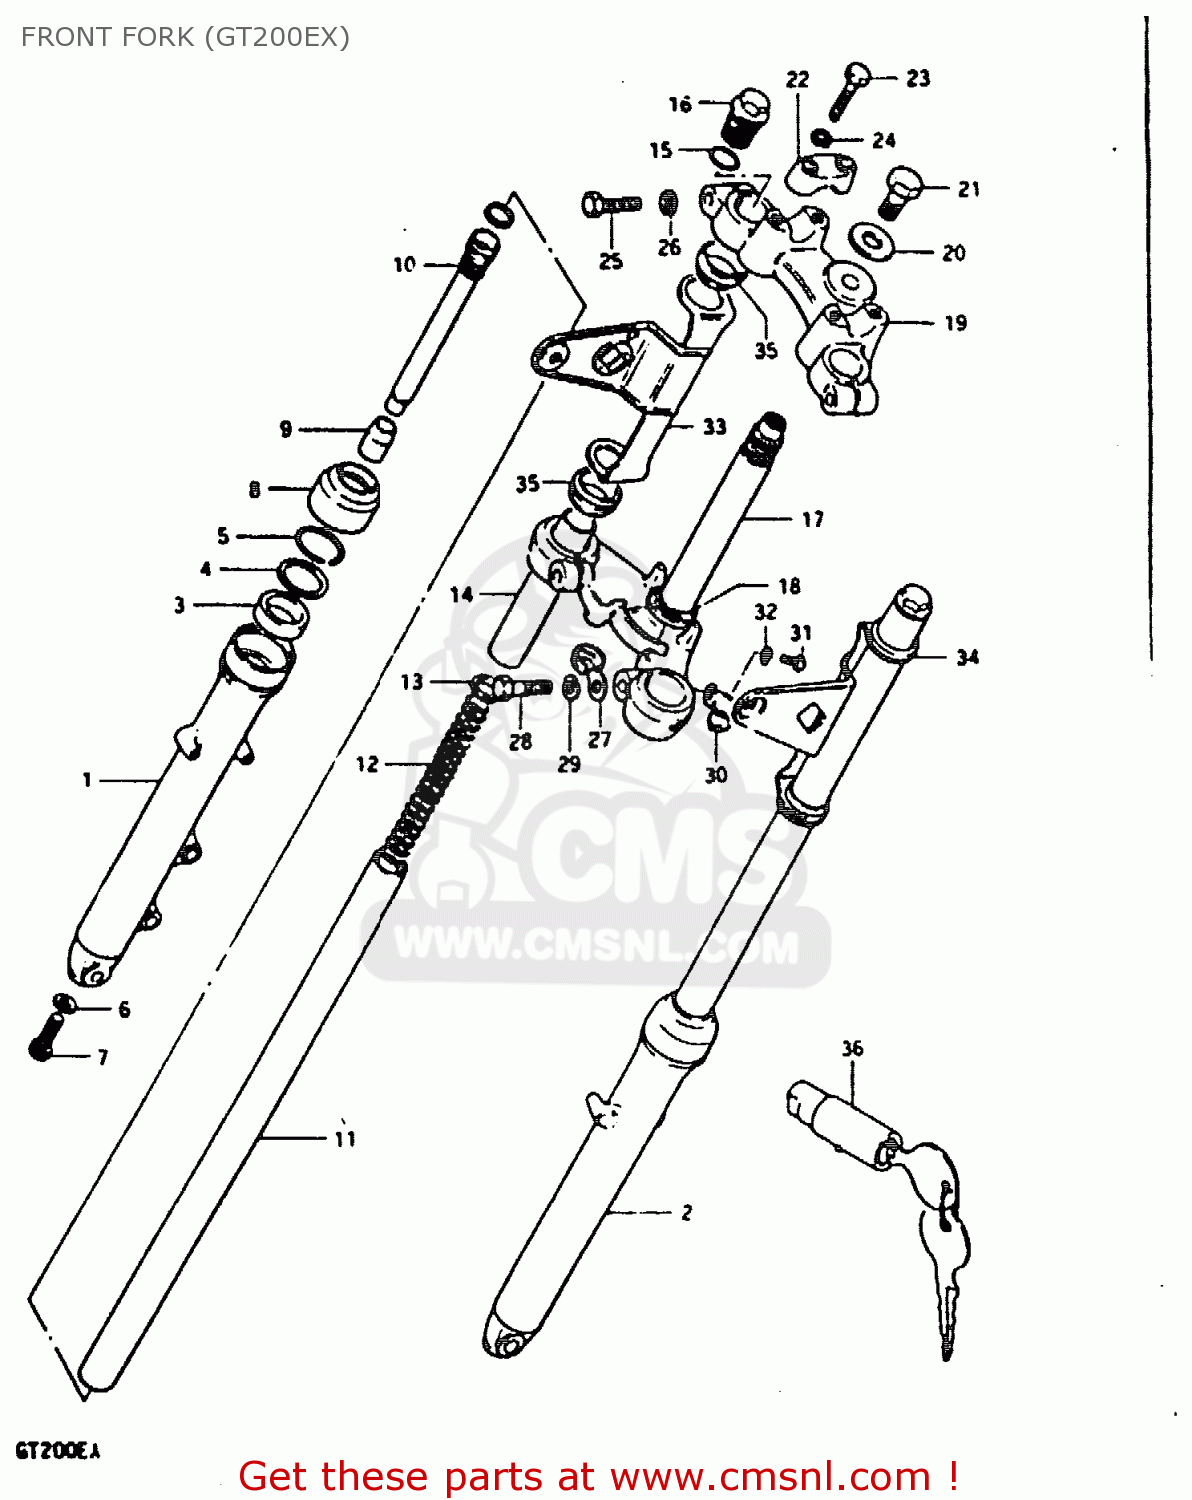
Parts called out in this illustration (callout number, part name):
1	OUTER TUBE, RH
2	OUTER TUBE, LH
3	OIL SEAL,FRONT FORK
4	WASHER,FRONT FORK
5	RING,SNAP
6	GASKET (NAS)
7	BOLT,FORK CYLINDER(10X25)
8	SEAL,DUST
9	PIECE,OIL LOCK
10	CYLINDER
11	INNER TUBE
12	SPRING
13	GUIDE,SPRING COVER
14	SPACER
15	O-RING,FORK INNER TUBE
16	BOLT,FR FORK
17	STEERING STEM
18	RACE,STEERING OUTER LWR
19	HEAD,STEERING STEM
20	WASHER,STEM HEAD(10.5X30X3.2)
21	BOLT,FORK INNER TUBE
22	HOLDER,HANDLE(BLACK)
23	BOLT
24	LOCK WASHER
25	BOLT,FORK INNER TUBE F
26	LOCK WASHER
27	CLIP
28	BOLT,FR FORK LWR(12X33)
29	WASHER,LOCK 12
30	CLIP,BRAKE CABLE
31	SCREW
32	LOCK WASHER
33	BRACKET, HEADLAMP RH
34	BRACKET, HEADLAMP LH
35	CUSHION
